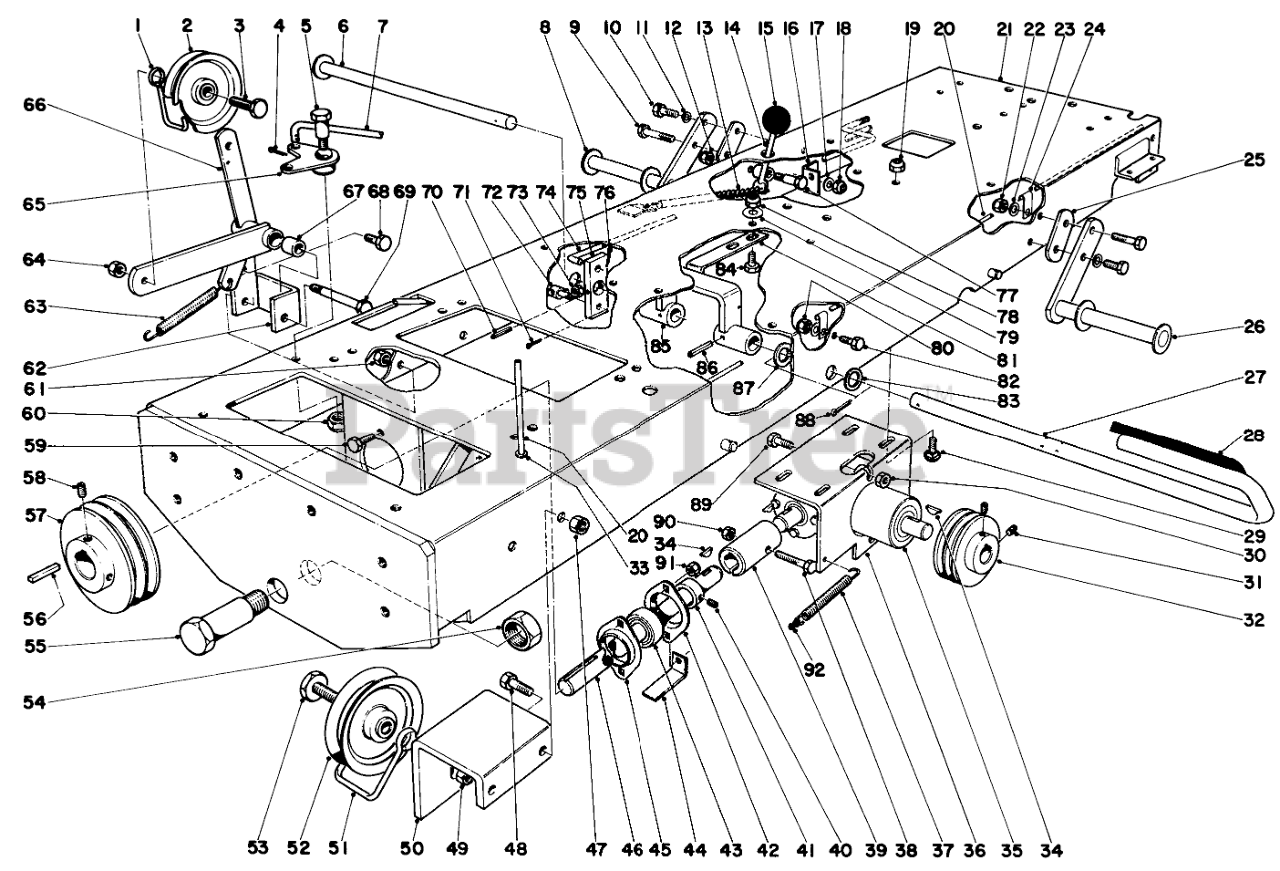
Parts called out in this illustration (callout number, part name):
1	Belt Retainer
2	IDLER PULLEY
3	Leveler Head Bolt
4	PIN-COTTER
6	Brake Shaft
7	Idler Rod
8	Bracket Foot Rest
9	SCREW-HH
10	SCREW-HH
11	WASHER-LOCK
12	Nut
13	IDLER ARM SPRING
14	Brake Lock
15	Knob
16	Brake Rod Retainer
17	WASHER-FLAT
19	Nut
20	Gas Line
21	Chassis 950
23	WASHER-FLAT
25	Spacer Foot Rest
26	Bracket Foot Rest
27	Brake Crank Arm
28	PAD-BRAKE
29	BOLT-CARR
31	SCREW-SET
32	Pulley Drive
33	Nyliner
34	KEY-WOODRUFF
35	Gear Box
36	Bracket Right Angle Gear Box
37	Spring
38	SCREW-HH
39	Coupling
40	SCREW-SET, HSH
41	Collar
42	Bearing Flange
43	Bearing
44	Belt Guide
45	Bearing Incl. Ref. 41-43
46	Drive Shaft
47	Nut
48	SCREW-HH
50	Idler Bracket
51	Belt Retainer
52	IDLER PULLEY
53	Leveler Head Bolt
55	Pivot Bolt
57	Pulley Drive
58	SCREW-SET
59	SCREW-HH
60	NUT-JAM
62	Mounting Bracket Idler
63	Spring
65	Bell Crank
66	Idler Arm Incl. Ref. No. 67
67	Bushing
68	SCREW-HH
69	Shoulder Bolt
70	Roll Pin
71	PIN-COTTER
72	Pivot Clutch Rod
74	Brake Rod
75	Bracket Idler
76	PIN-COTTER
78	Nut
79	Washer
80	Nut
81	Stop Brake Pedal
82	SCREW-HH
83	Washer
84	SCREW-HH
85	Bracket Assy.
86	Roll Pin
87	Washer
88	PIN-COTTER
89	SCREW-HH
90	Nut
91	Nut
92	S-Hook
